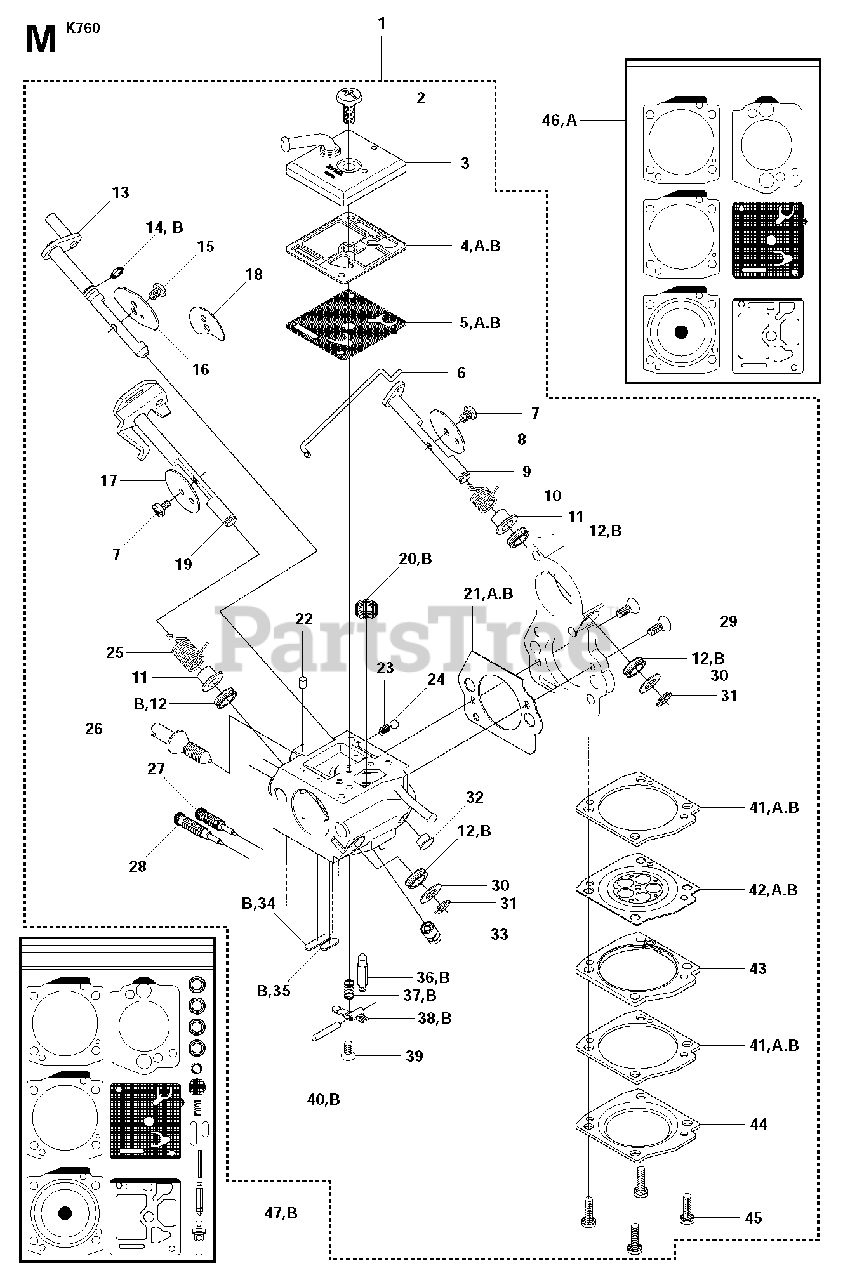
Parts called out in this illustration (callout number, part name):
1	CARBURETTORZama C3-EL43A, Incl. 2 - 43
5	DIAPHRAGM PUMP
18	CHOKE VALVEJapan only
40	PIN RETAINING SCREW
42	DIAPHRAGM ASSY
46	GASKET KITIncl. 4-5, 21, 41, 42
47	GASKET KITIncl. 4-5, 12, 14, 20, 21, 34-38, 40-42
